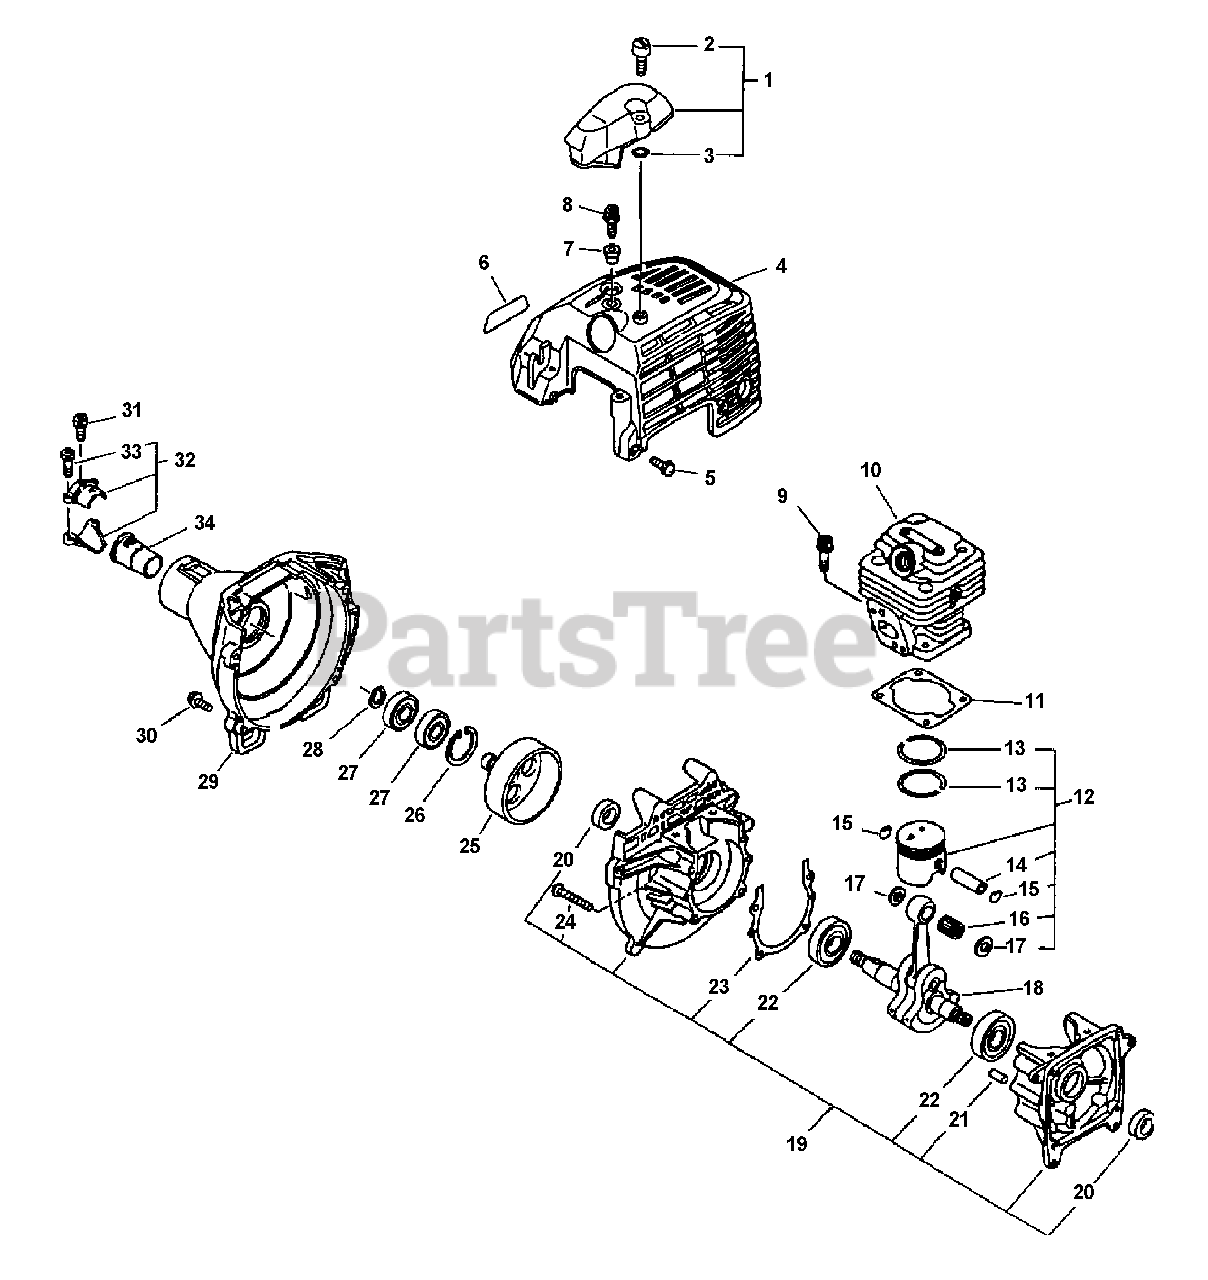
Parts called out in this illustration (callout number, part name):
1	GUARD KIT
2	KNOB, FASTENER
3	O-RING - 4
4	COVER, ENGINE
5	SCREW - 5X12
6	LABEL - MODEL PE-3100
8	SCREW - 5X20
9	SCREW - 5X20
10	CYLINDER
11	GASKET, CYLINDER
12	PISTON KIT
13	RING, PISTON
14	PIN, PISTON
15	RING, RETAINING
16	BEARING, NEEDLE
17	SPACER, PISTON
18	CRANKSHAFT ASSY
19	CRANKCASE KIT
20	SEAL, OIL
21	PIN - LOCATING
22	BEARING, BALL - 6201
23	GASKET, CRANKCASE
24	SCREW - 5X30
25	DRUM, CLUTCH
26	RING, RETAINING - 28
27	BEARING, BALL - 6001
28	RING, RETAINING - 12
29	CASE, FAN
30	SCREW - 5X20
31	SCREW - 5X12
32	HOLDER KIT
33	SCREW - 5X25
